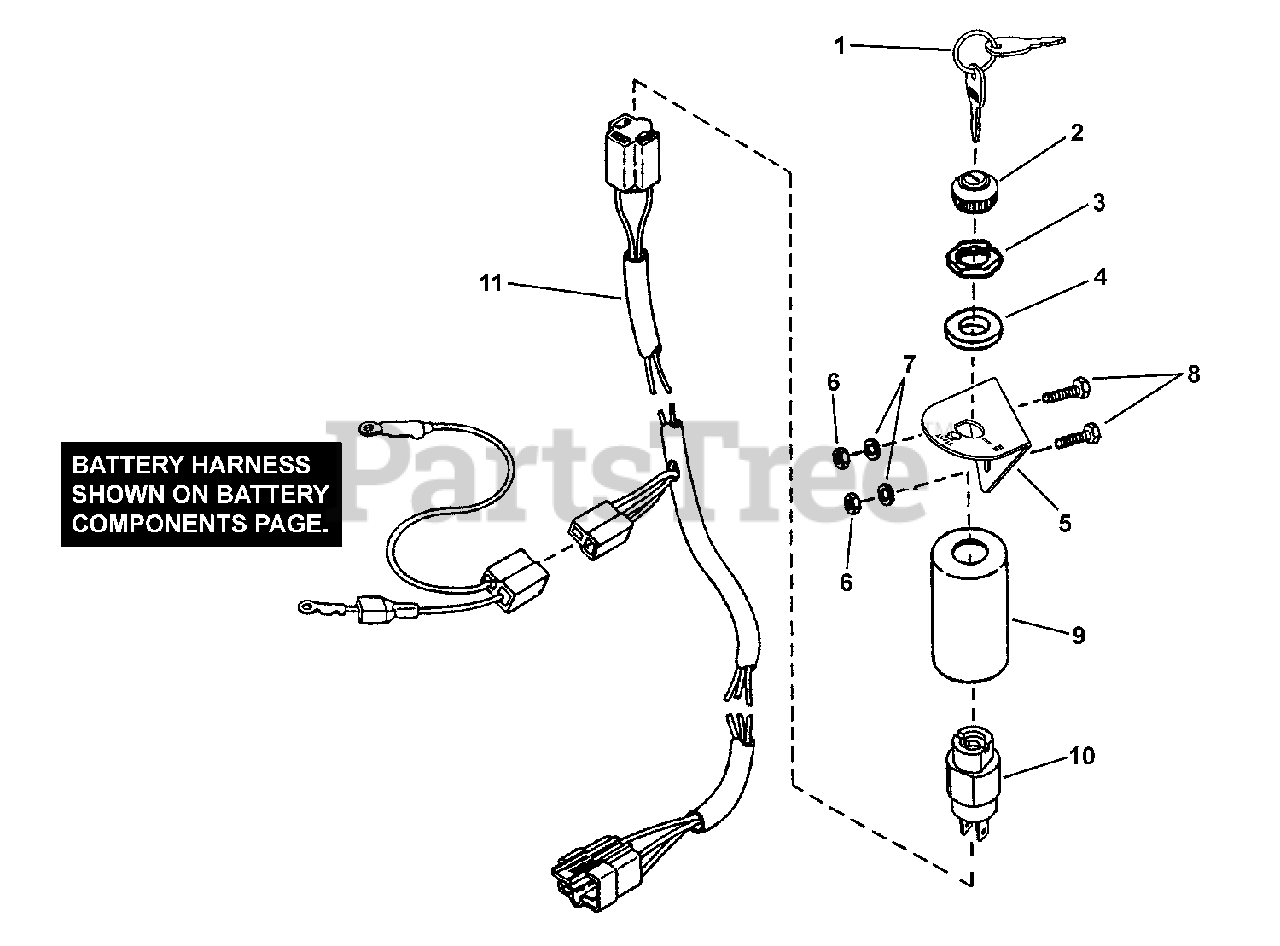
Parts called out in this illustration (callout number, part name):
1	KEY (Set of Two)
2	BEZEL
3	NUT, 5/8-32 Hex Lock
4	SPACER
5	BRACKET, Ignition Switch
6	NUT, 1/4-28 Hex
7	WASHER, 1/4" Internal Tooth Lock
8	SCREW, 1/4-28 x 1-3/8" Hex Head Cap, GR 5
9	COVER, Switch
10	SWITCH, Ignition
11	HARNESS, wiring
